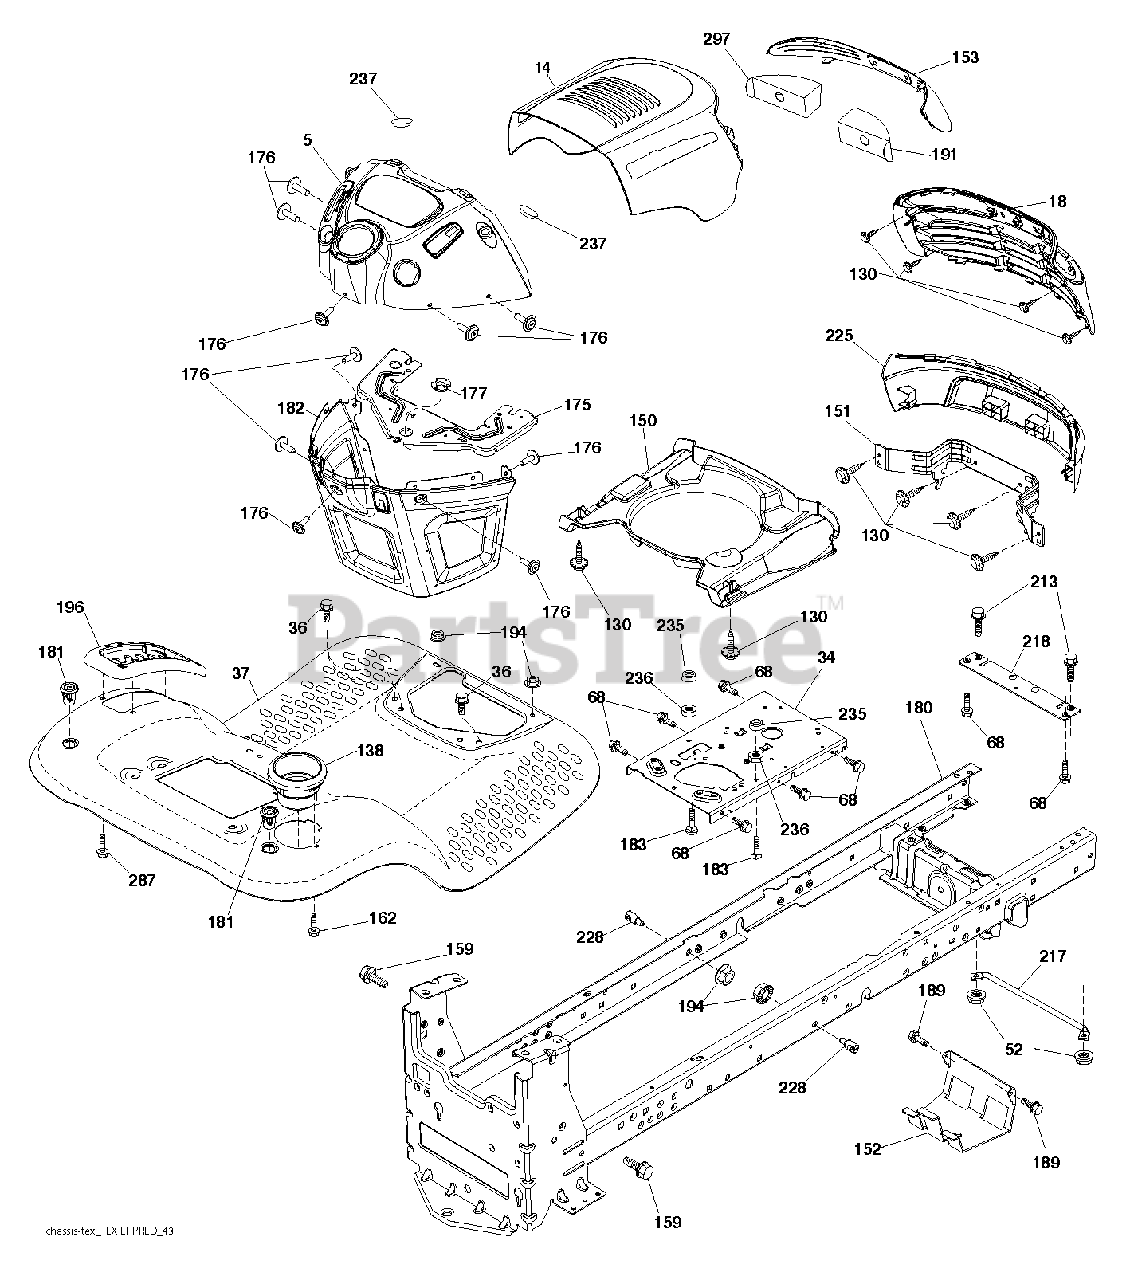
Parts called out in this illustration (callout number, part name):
68	SCREW LT
130	SCREW.#10 X 0.750.BOS THREAD
138	CUPHOLDER
152	SHIELD BROWNING
159	SCREW, 3/8-16X3/4
162	SCREW,HEX
176	SCREW.#10-24X5/8.RN.QU
180	CHASSIS
181	FEND/FTRST.PCH.CPH.NFW
183	BOLT.5/16-18X1-1/4 FULL THD
189	SCREW
194	NUT LOCK HEX FLANGE 5/16-18
196	CONSOLE ASM. DECK LIFT
228	STUD.FASTNER.W/D.ANTI-
235	SPACER FENDER
236	JAM LOCK NUT
